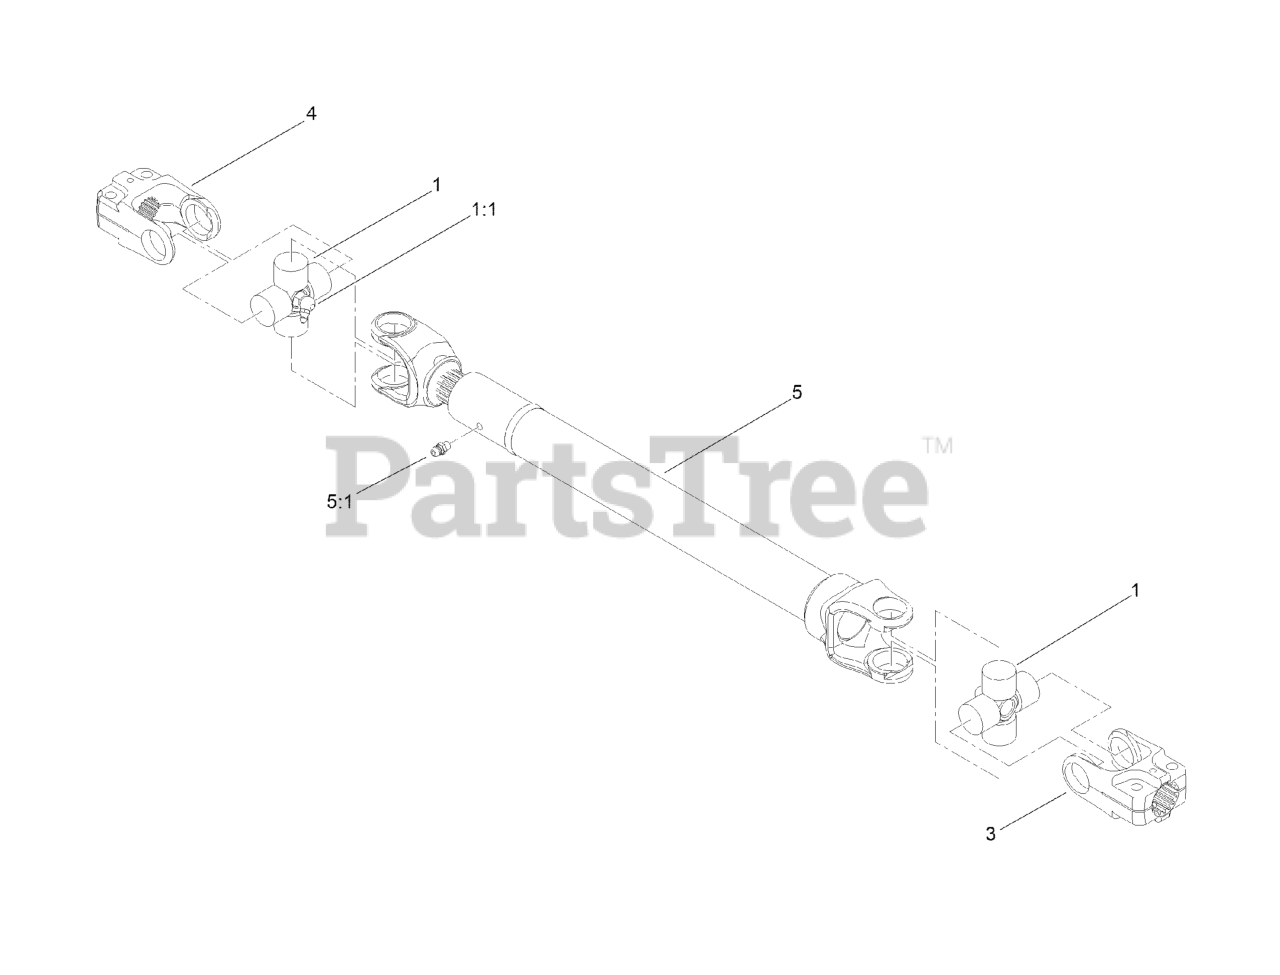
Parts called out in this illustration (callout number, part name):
1	CROSS AND BEARING KIT
1:1	FITTING-GREASE
3	YOKE-END
4	YOKE-END
5	Tube-Yoke, Slip
5:1	FITTING-GREASE
